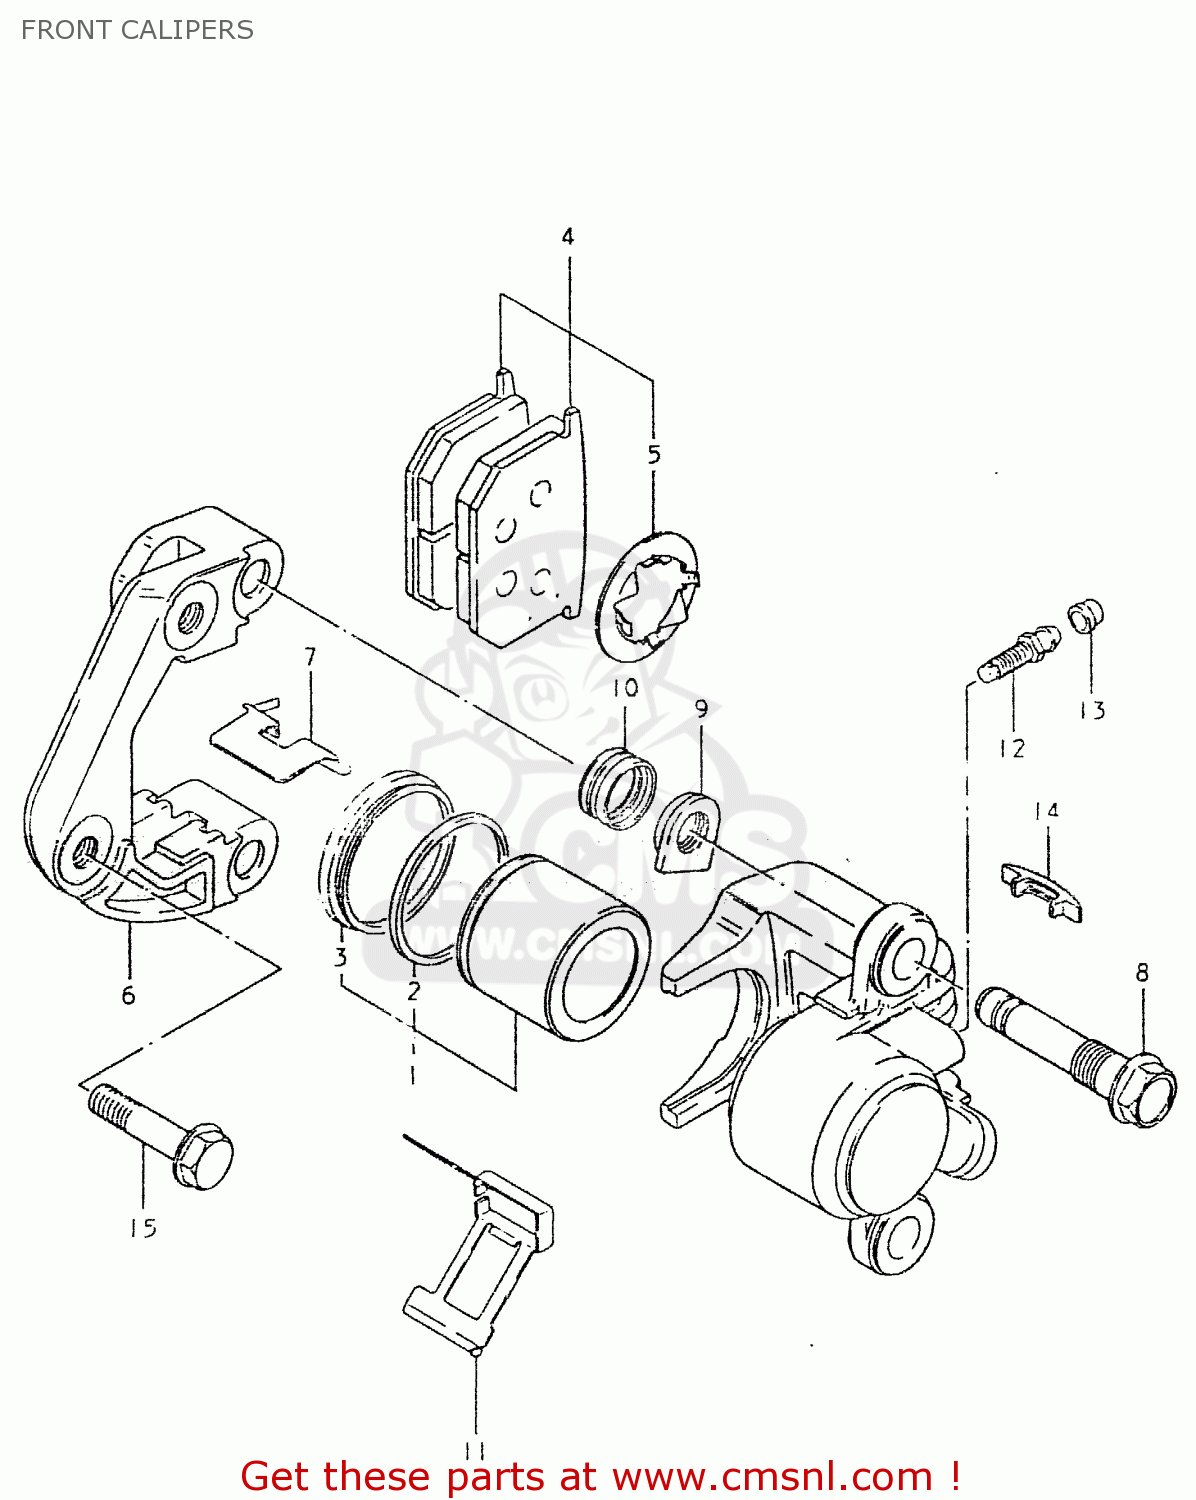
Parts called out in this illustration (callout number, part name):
1	PISTON SET
2	SEAL,PISTON
3	BOOT,PISTON
4	PAD & SHIM SET (MCA)
5	SHIM,PAD
6	HOLDER,CALIPER,LEFT
7	GUIDE,PAD
8	AXLE,CALIPER
9	NUT,CALIPER AXLE
10	BOOT
11	SPRING
12	BREATHER
13	CAP,BLEEDER PL
14	COVER,INDICATOR
15	BOLT
